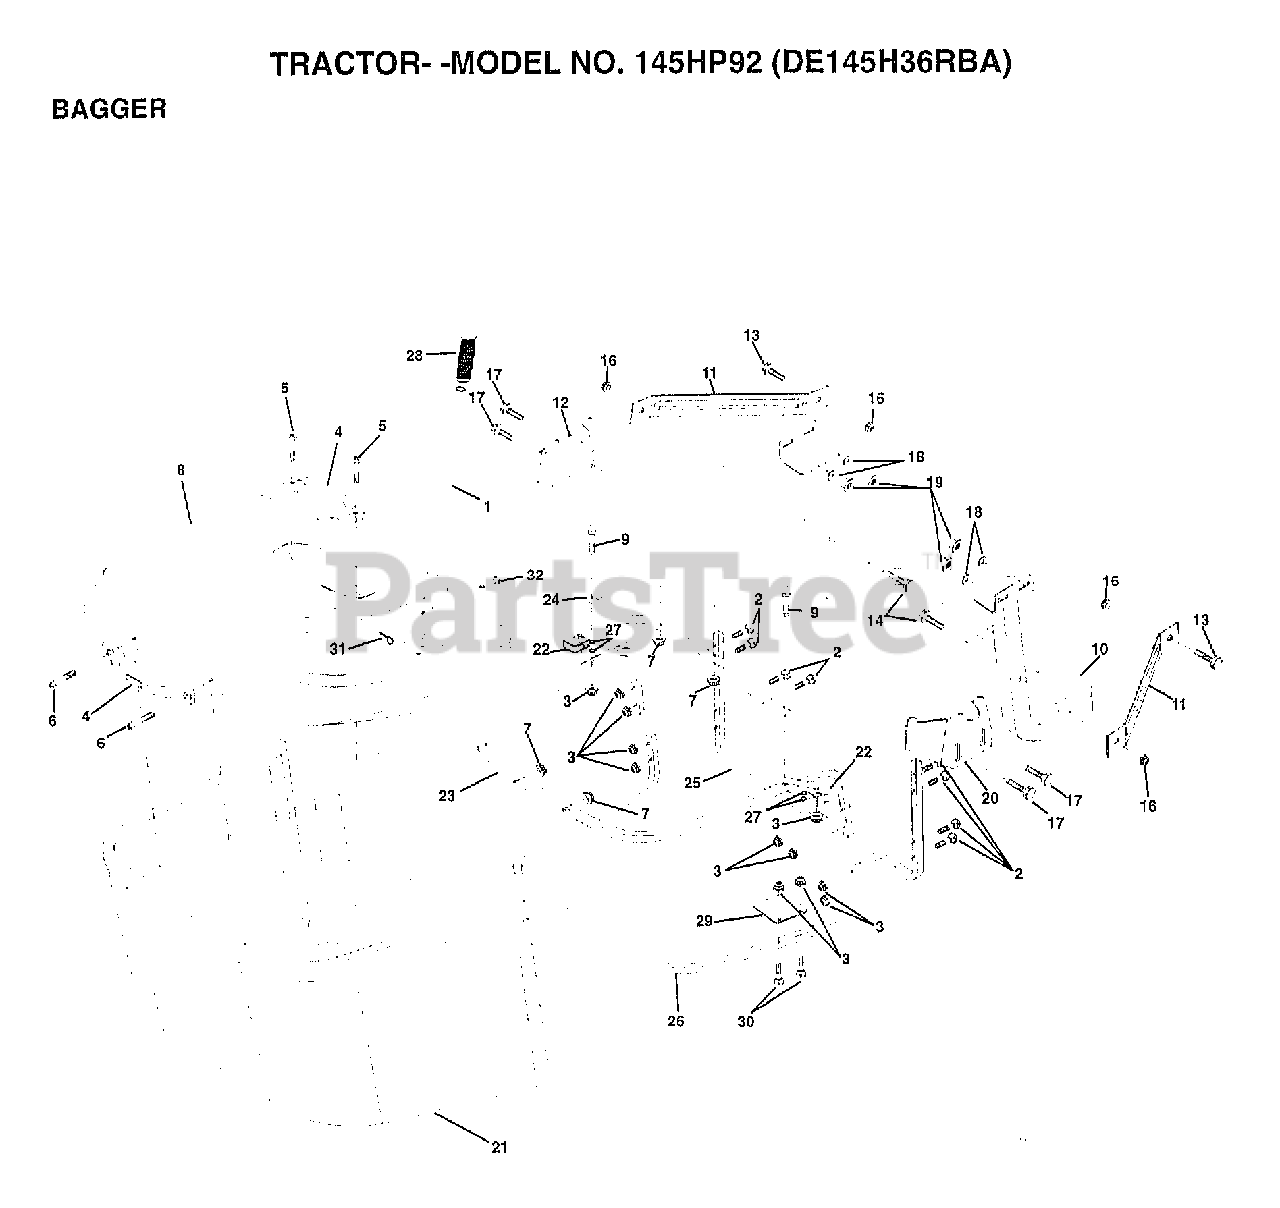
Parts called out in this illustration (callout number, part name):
1	TUBE.HDLE.BAG.CRD
2	BOLT.CARRIAGE.1/4-20X2.0
4	HANDLE.GRAB.BLACK.
5	"SCREW,PAN.HEAD"
8	COVER.BAGGER.CRD
9	BOLT CARRIAGE
10	SUPT.ASM.WLDMNT.BAG.CRD
11	BRKT.SUPT.UPPER.BAG.CRD
12	BRKT.PIVOT.BAG.LH.CRD
13	BOLT
14	BOLT.HEX.3/8-16X2-1/2
17	BOLT
18	WASHER
19	NUT
20	"BRKT.PIVOT.BAG,RH.CRD"
21	BAG.ASM.CRD
22	BRKT.SIDE.BAG.CRD
23	TUBE.UPPER.BAG.CRD
24	TUBE.PIVOT.BAG.CRD
25	TUBE.FT.BAG.CRD
26	TUBE.LOWER.BAG.CRD.
27	GROMMET.EXTRUDED
28	GRIP.HANDLE.BLACK
29	PLATE.STOP.BAG.HDLE.CRD
30	BOLT.CARRIAGE
31	RETAINER M
32	RIVET.DRILL.1.75
